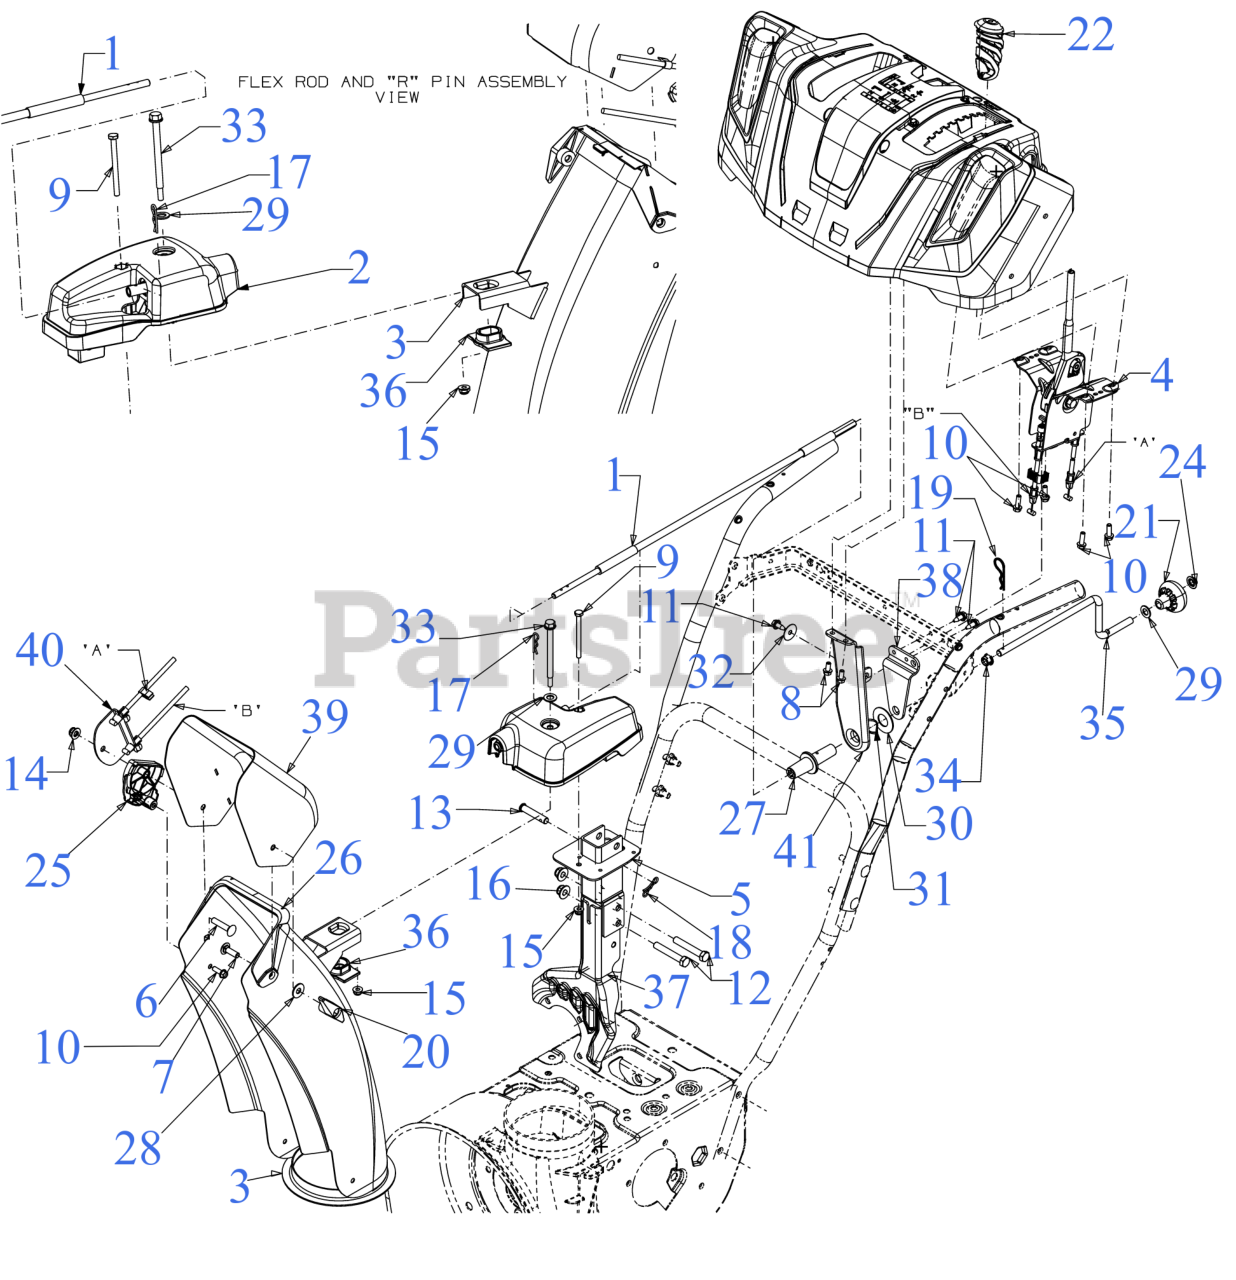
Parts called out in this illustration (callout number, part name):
1	CHUTE CONTROL
2	2-WAY CHUTE ROTATE GEARBOX
4	2-WAY STEEL CHUTE CONTROL ASSEMBLY
5	EXTENSION CHUTE MAST
6	CARRIAGE BOLT 5/16-18 x 1.50
7	CARRIAGE BOLT 5/16-18 x 1.00
8	HEX SCREW 1/4-15 x .50
9	SCREW 1/4-20 x 3.0 GR5
10	SCREW 1/4-15 x .750
11	SCREW 1/4-20X.625
12	SCREW 3/8-16 x 2.25 GR5
13	CLEVIS PIN 3/8 x 1.87
14	FLANGE LOCK NUT 5/16-18
15	FLANGE LOCK NUT
17	INTERNAL COTTER PIN
18	BOW TIE COTTER PIN 1/4-5/16
19	INTERNAL COTTER PIN
20	WING KNOB NUT
21	SHIFT KNOB
22	PTO HANDLE GRIP .355 ID
25	CHUTE TILT GUIDE
26	UPPER CHUTE ADAPTER
27	CHUTE ROD COUPLER
28	FLAT WASHER
29	FLAT WASHER
30	FLAT WASHER
31	WAVE WASHER .785X1.00X.012
32	FLAT WASHER
33	SHOULDER SCREW
34	BUSHING .380 ID
35	CHUTE CRANK (POWDER BLACK)
36	HELICAL GEAR CHUTE ADAPTER
38	ROD SUPPORT BRACKET
